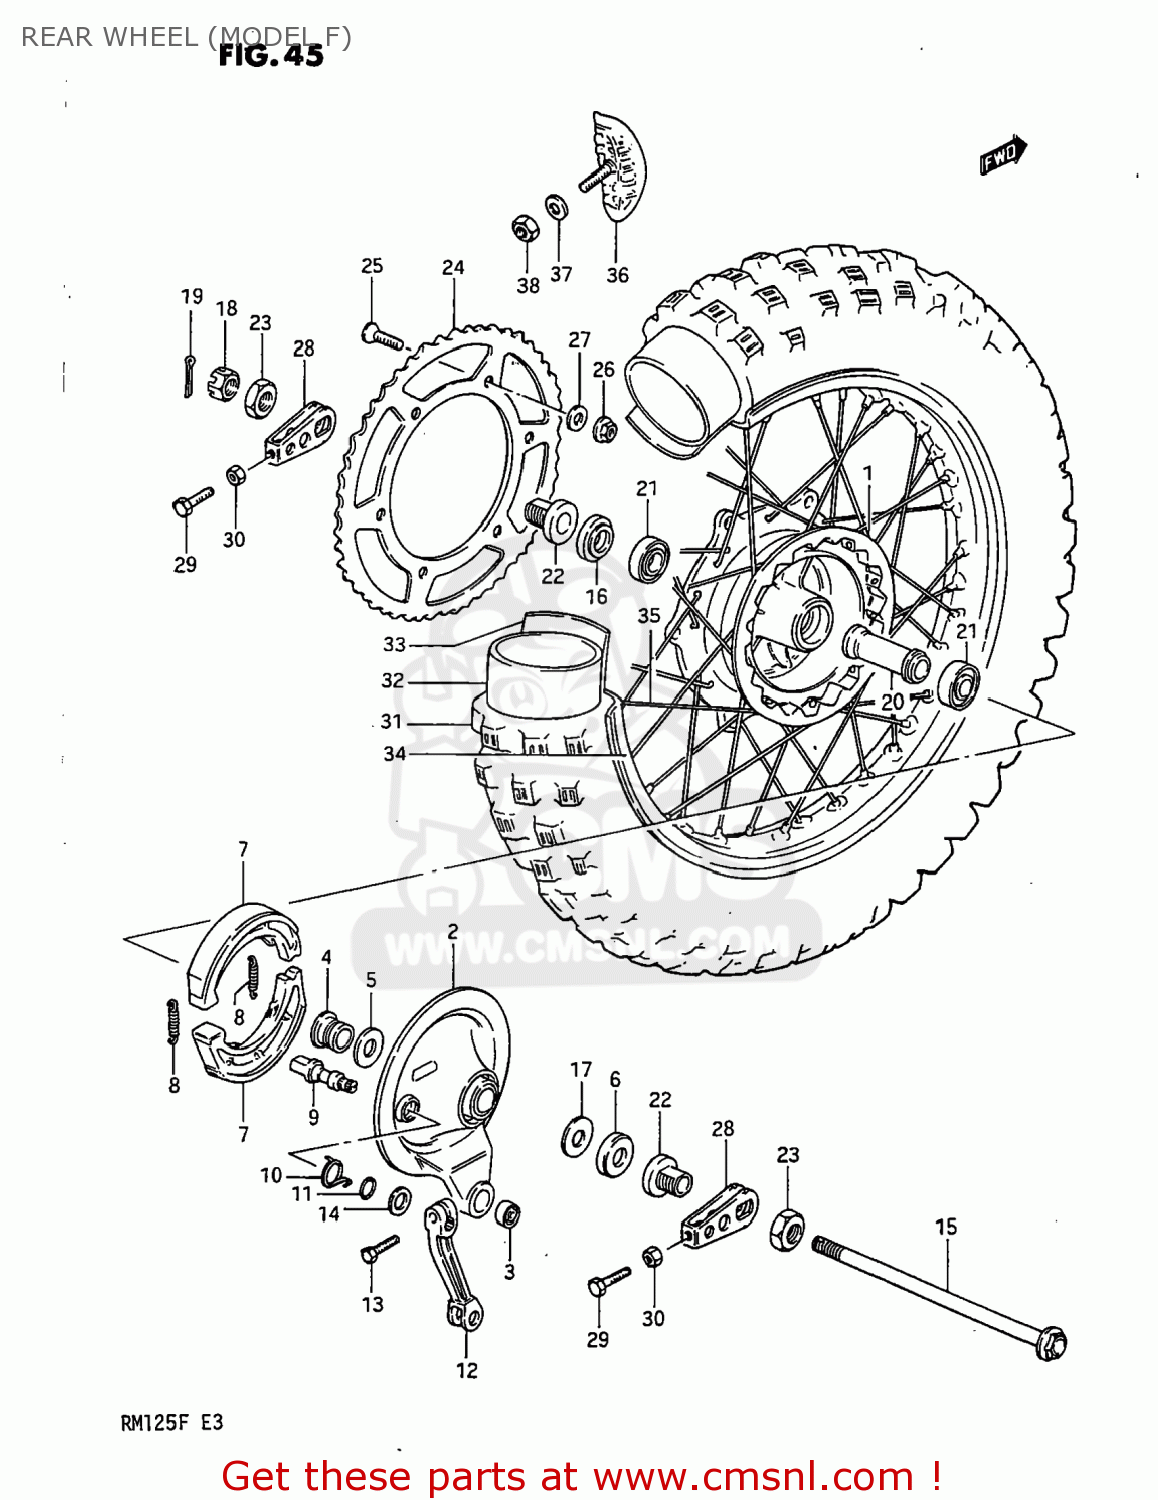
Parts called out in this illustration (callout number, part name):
1	DRUM,REAR HUB
2	PANEL SET,REAR HUB
3	BEARING
4	SPACER,RR BRAKE ANCHOR PANEL
5	SEAL,OIL(20X27X5)
6	CVR,RR BRAKE AHR PNL DUST SEAL
7	SHOE,BRAKE (MCA)
8	SPRING(L:34)
9	CAM,FR BRAKE
10	SPRING
11	O RING(D:2.5,ID:11.4)
12	LEVER,REAR BRAKE CAM
13	BOLT
14	WASHER(12.5X20X1)
15	AXLE,REAR.
16	SPACER,RR AXLE,L
17	WASHER,THRUST
18	NUT
19	COTTER PIN
20	SPACER
21	BEARING
22	SPACER,CHAIN ADJUSTER
23	NUT
24	SPROCKET,REAR
25	SCREW(8X33.5)
26	NUT
27	WASHER
28	ADJUSTER,CHAIN
29	BOLT
30	NUT
31	TIRE
32	TUBE ASSEMBLY,WHEEL,INNER
33	PROTECTOR
34	RIM,REAR WHEEL (1.85X18)
35	SPOKE SET,REAR
36	STOPPER,BEAD
37	WASHER
38	NUT
